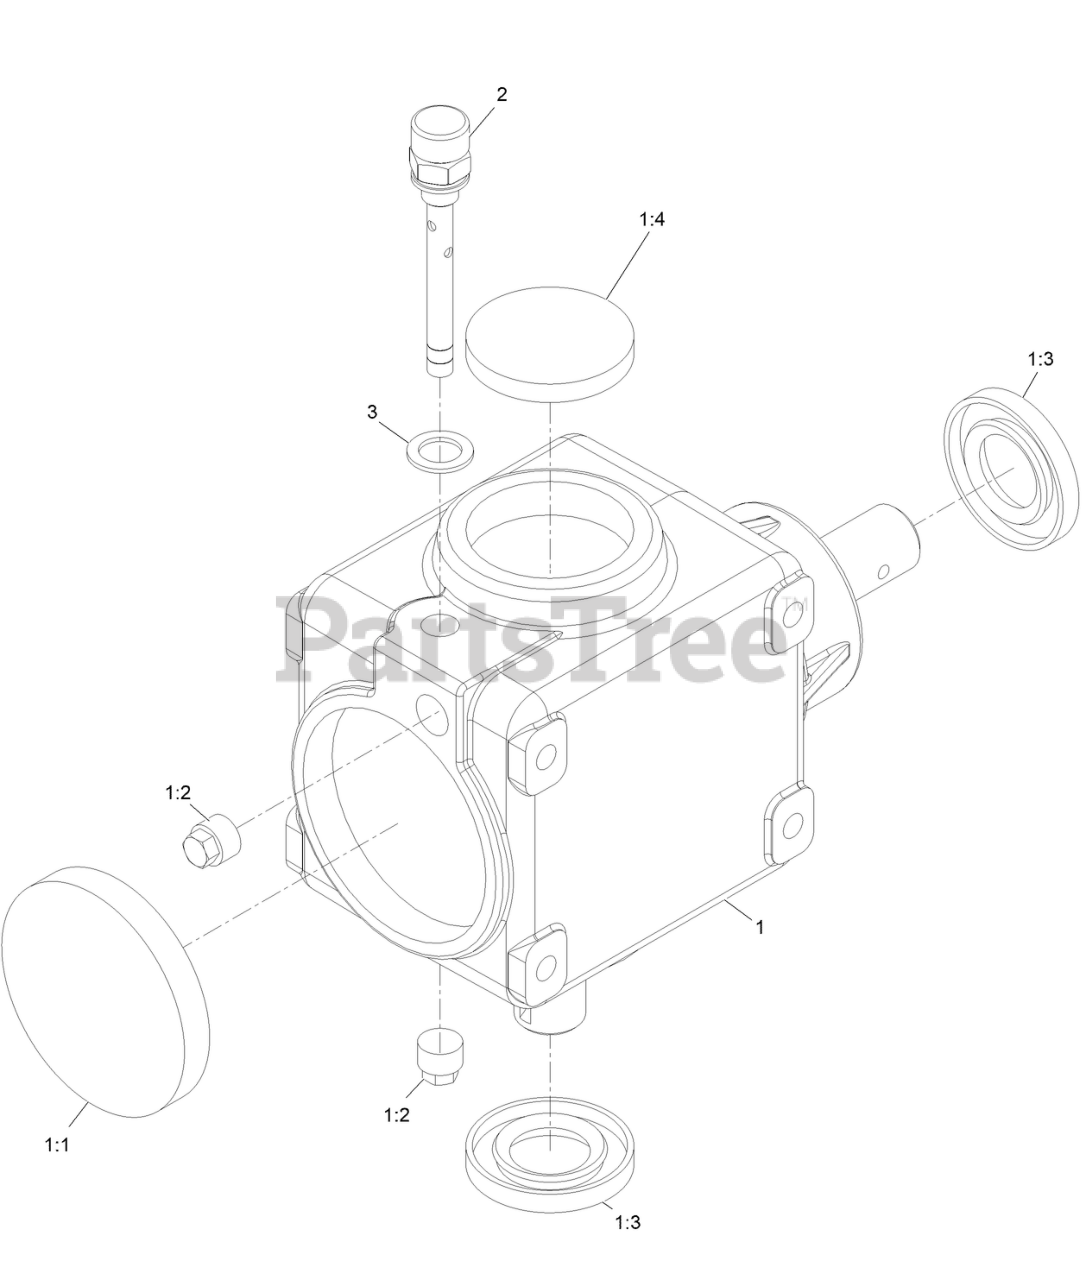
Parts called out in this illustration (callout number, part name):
1	GEARBOX ASM-90 DEG
1:1	CAP-OIL
1:4	CAP-OIL
2	PLUG-BREATHER
3	WASHER
